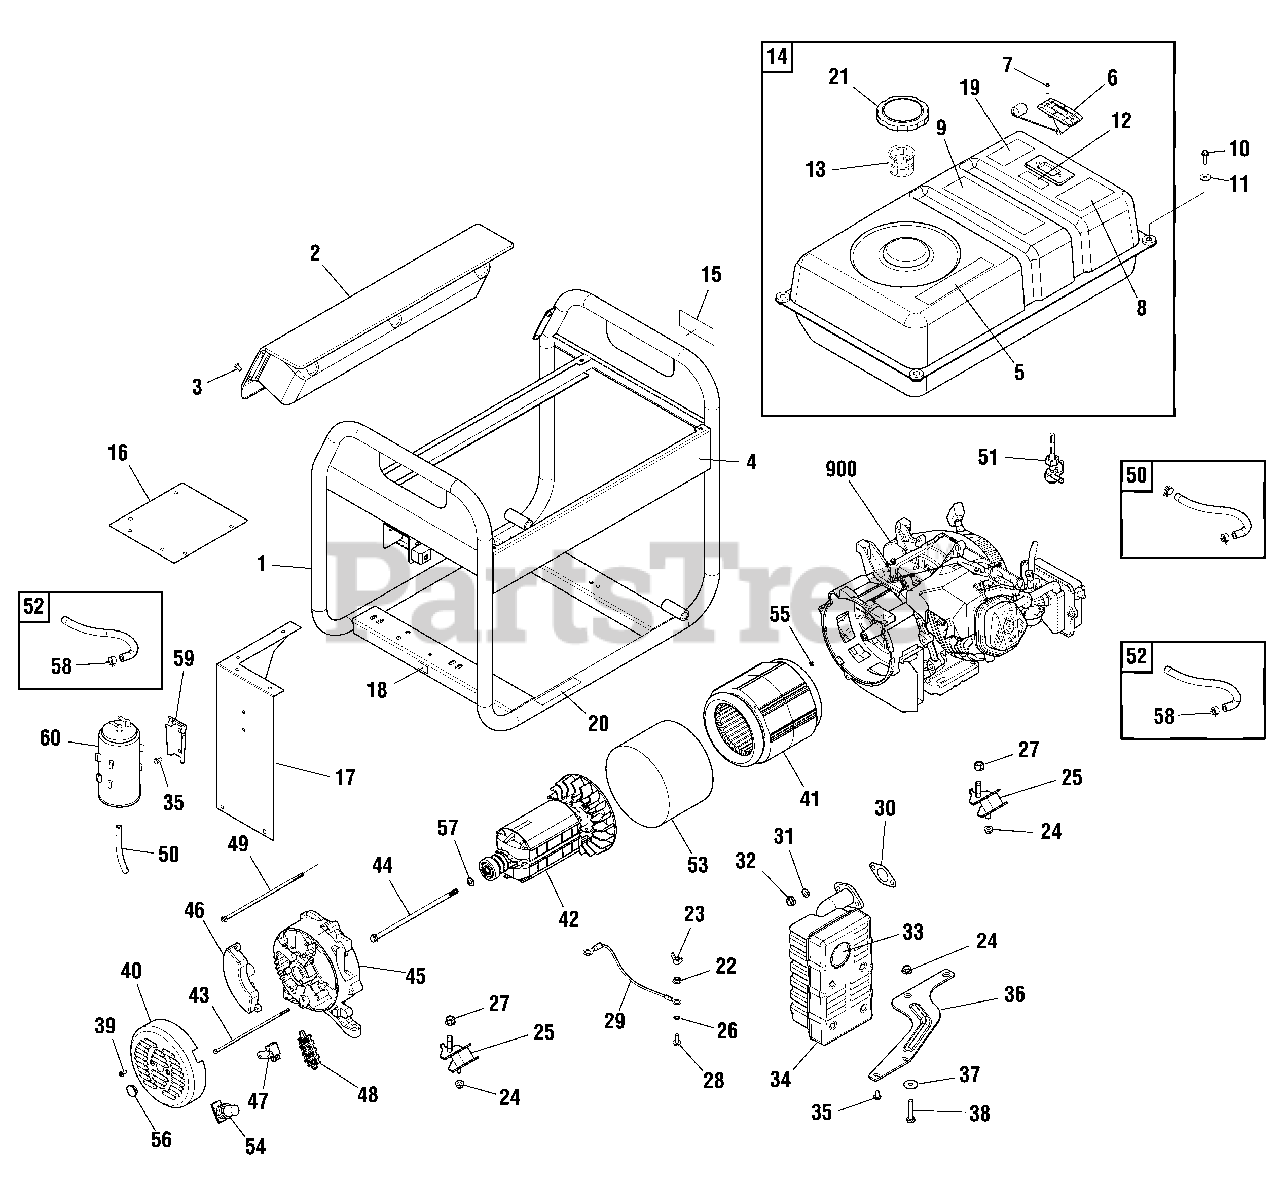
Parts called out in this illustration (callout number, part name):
2	PANEL-CONTROL
22	* NUT, Flange Lock, M6
24	* NUT, Flange Lock, M8
25	MOUNT-VIBRATION
26	* WASHER, Shakeproof, Ext M6
27	* NUT, Flange Lock, M10
28	* SCREW, Flange, M6 x 16
30	GASKET
31	* WASHER, Lock, M8
32	* NUT, Hex, M8 1.25
35	* SCREW, Flange, M6 x 12
36	BRACKET-MUFFLER
37	* WASHER, Flat, M8
38	CAPSCREW-HEX HEAD, M8-1.25 x 40
45	CARRIER-BEARING
46	VOLTAGE REGULATOR
50	KIT-FUEL HOSE
52	HOSE-VAPOR
900	** ENGINE
